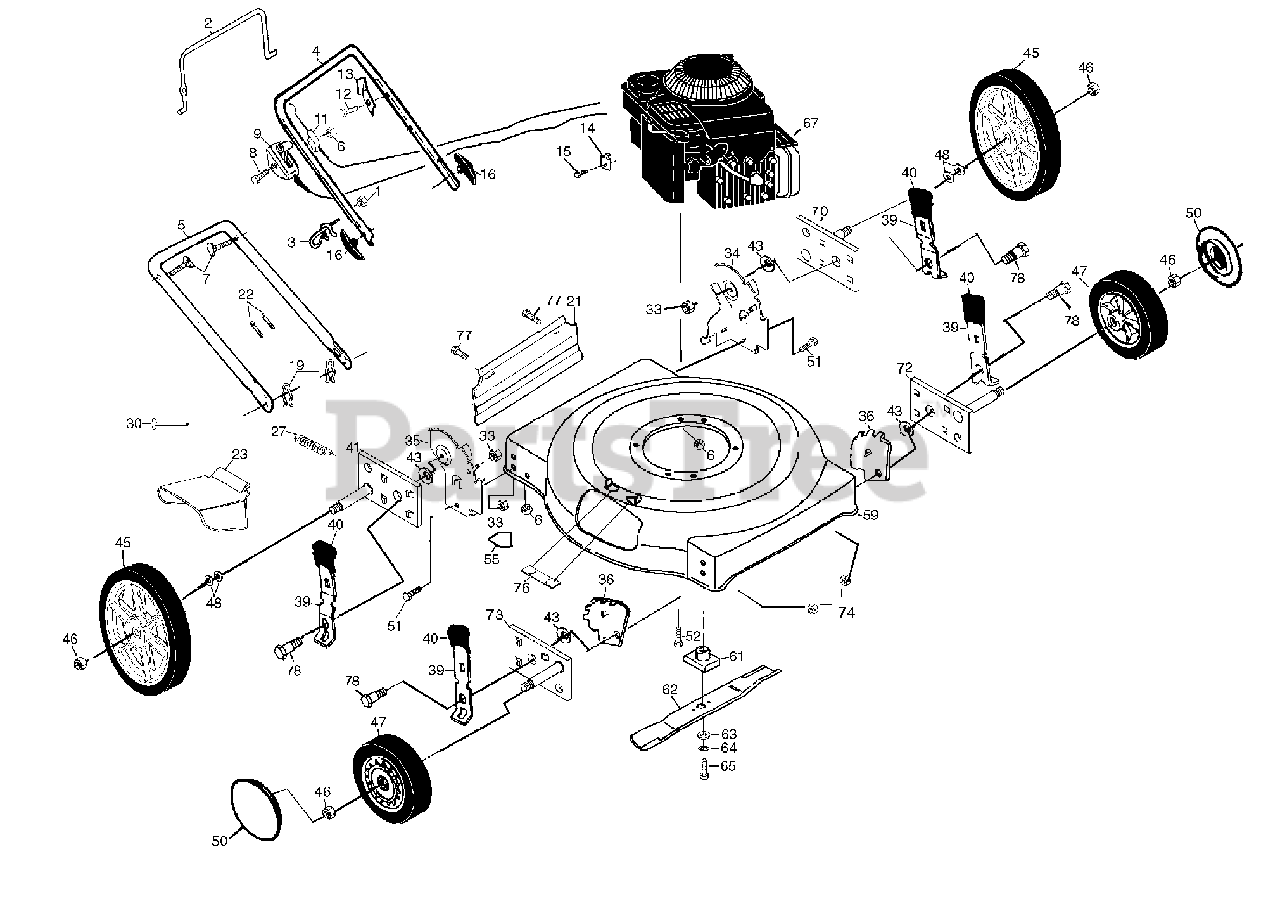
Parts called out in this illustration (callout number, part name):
1	Locknut 1/4-20
2	Control Bar
3	Rope Guide
4	Upper Handle
5	Lower Handle
6	Locknut 1/4-20
7	Handle Bolt 5/16-18
8	Hex Washer Head Screw 1/4-20 x 2-1/8
9	Throttle Control
11	Engine Zone Control Cable
12	Hex Washer Head Screw #10-24 x 1/2
13	Up-Stop Bracket
14	Cable Clamp
15	Screw #10 x 5/8
16	Handle Knob
19	Hairpin Cotter
21	Rear Deflector
22	Wire Tie
23	Discharge Guard
27	Torsion Spring
30	Hinge Rod
33	Locknut 5/16-18
34	Wheel Bracket Support (Left)
35	Wheel Bracket Support (Right)
36	Wheel Bracket Adjuster
39	Selector Spring
40	Selector Knob
41	Axle Arm Assembly (RR)
43	Washer
45	Wheel Assembly (Rear)
46	Locknut 1/16-18
47	Wheel Assembly (Front)
48	Washer
50	Hubcap
51	Hex Head Bolt 5/16-18
52	Hex Head Thread Rolling Screw 3/8-16 x 1
55	Danger Decal
59	Lawn Mower Housing
61	Blade Adapter
62	22" Blade
63	Hardened Washer
64	Helical Lockwasher 3/8
65	Screw Hex Head 3/8-24 x 1-3/8 (Grd. 8)
70	AxleArm Assem.(LR)
72	AxleArm Assm. ((LF)
73	Axle Arm Assm. (RF)
74	Nut
76	Clip. Closeout
77	Screw
78	Shoulder Bolt
78	Operator's Manual (English)
78	Replacement Parts Manual
78	Grass Catcher
78	Mulcher Kit
